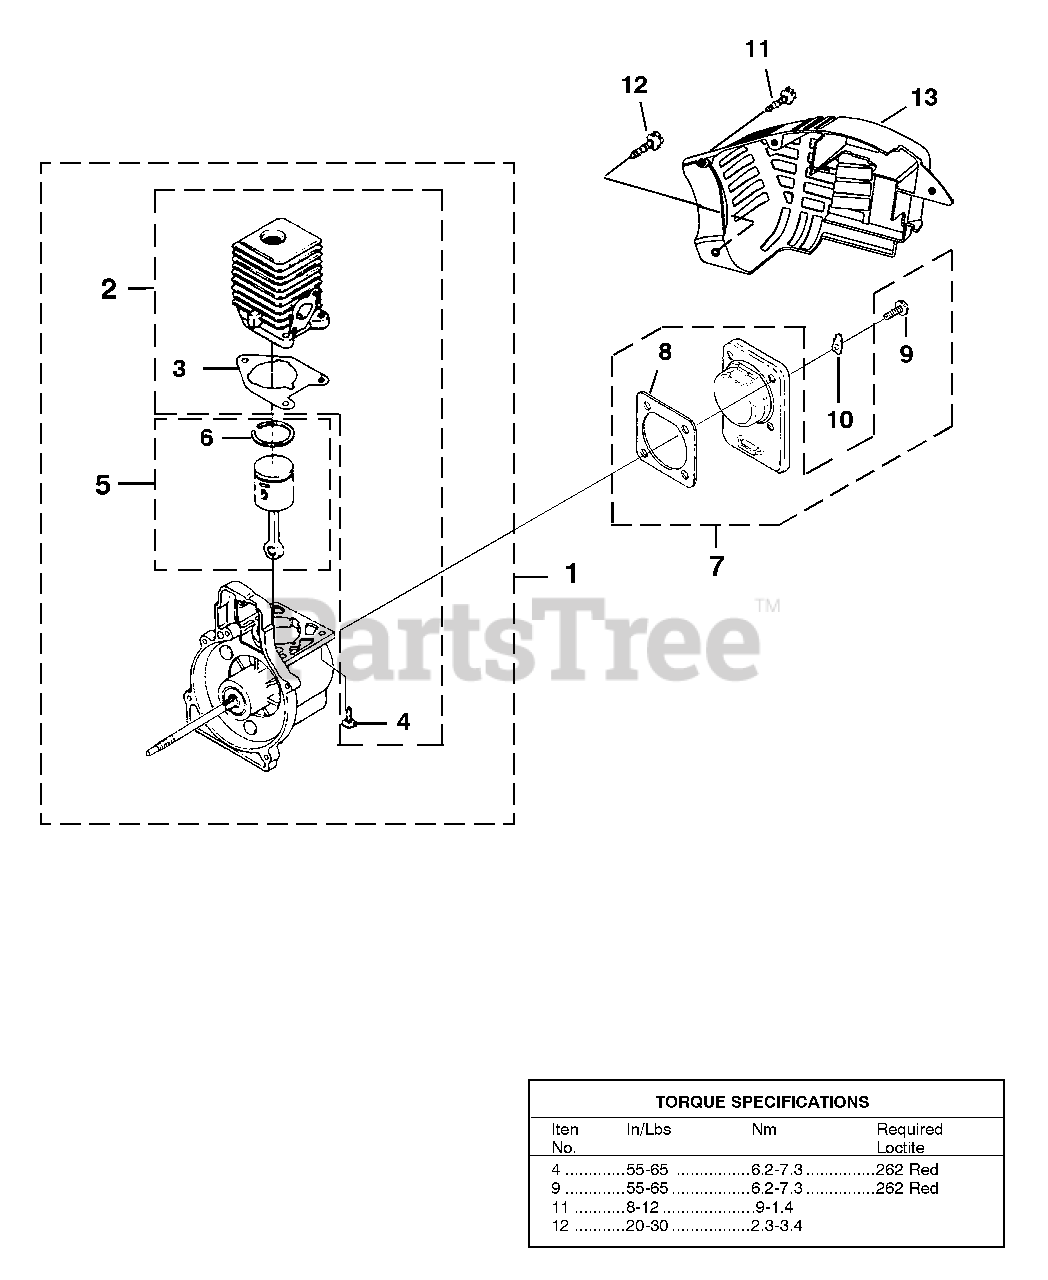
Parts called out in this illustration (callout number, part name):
1	SHORT BLOCK (30cc)
1	SHORT BLOCK (25cc)
2	30 CC CYLINDER KIT
2	25 CC CYLINDER KIT
3	GASKET-Cylinder
4	SCREW, SEMS (12-24 x 3/4)
5	30 CC PISTON & ROD
5	25 CC PISTON & ROD
6	RING-Piston
7	CRANKCASE COVER-Stamped Steel
8	GASKET-Crankcase
9	SCREW, SEMS (10-24 x .56)
10	TAB-Male
11	SCREW-Thread Form. (#8 X 1/2")
12	SCREW-Thread Form. (#10 X 3/4")
